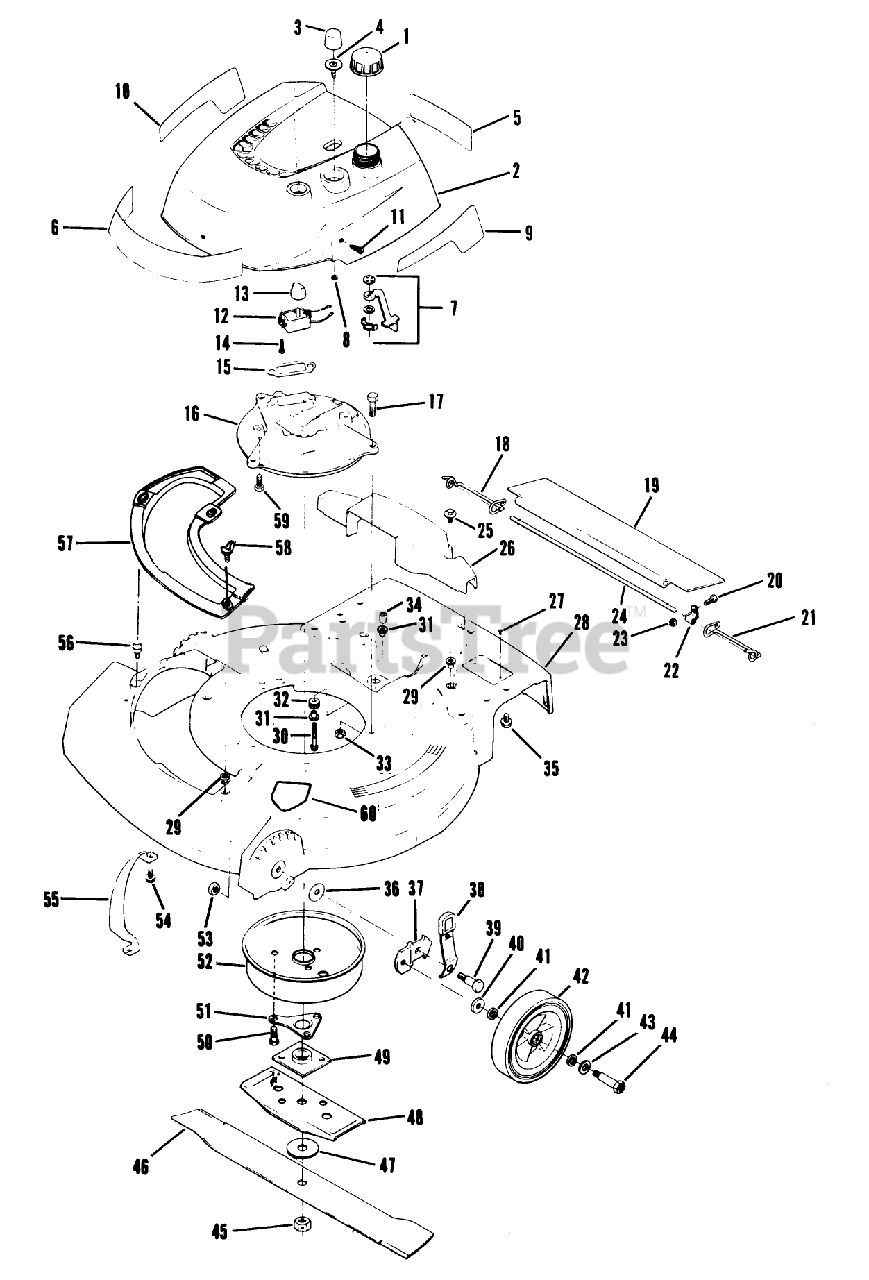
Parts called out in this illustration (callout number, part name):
3	P-BULB LAV-RUB
8	LOCKNUT S
11	SCREW S
18	SPRING;TRAILING SHIELD RH
21	SPRIG T/SHLD ASOC
22	CLAMP ROD KMC
23	LOCKNUT E
24	ROD 21" ADVANCE
25	SCREW SEMS TRM HEX HD
31	SPACER ECK PRES
32	GROMMET
33	NUT-LOCK F
40	WASHER WROUGHT
44	BOLT WHEEL
45	NUT-BLADE
49	PLATE AND COLLAR ASM
51	SUPPORT F
53	LOCKNUT
55	BAR-TOE
58	WING SCREW LAWRE
59	SCREW V
60	Decal-Blade Contact Warning
